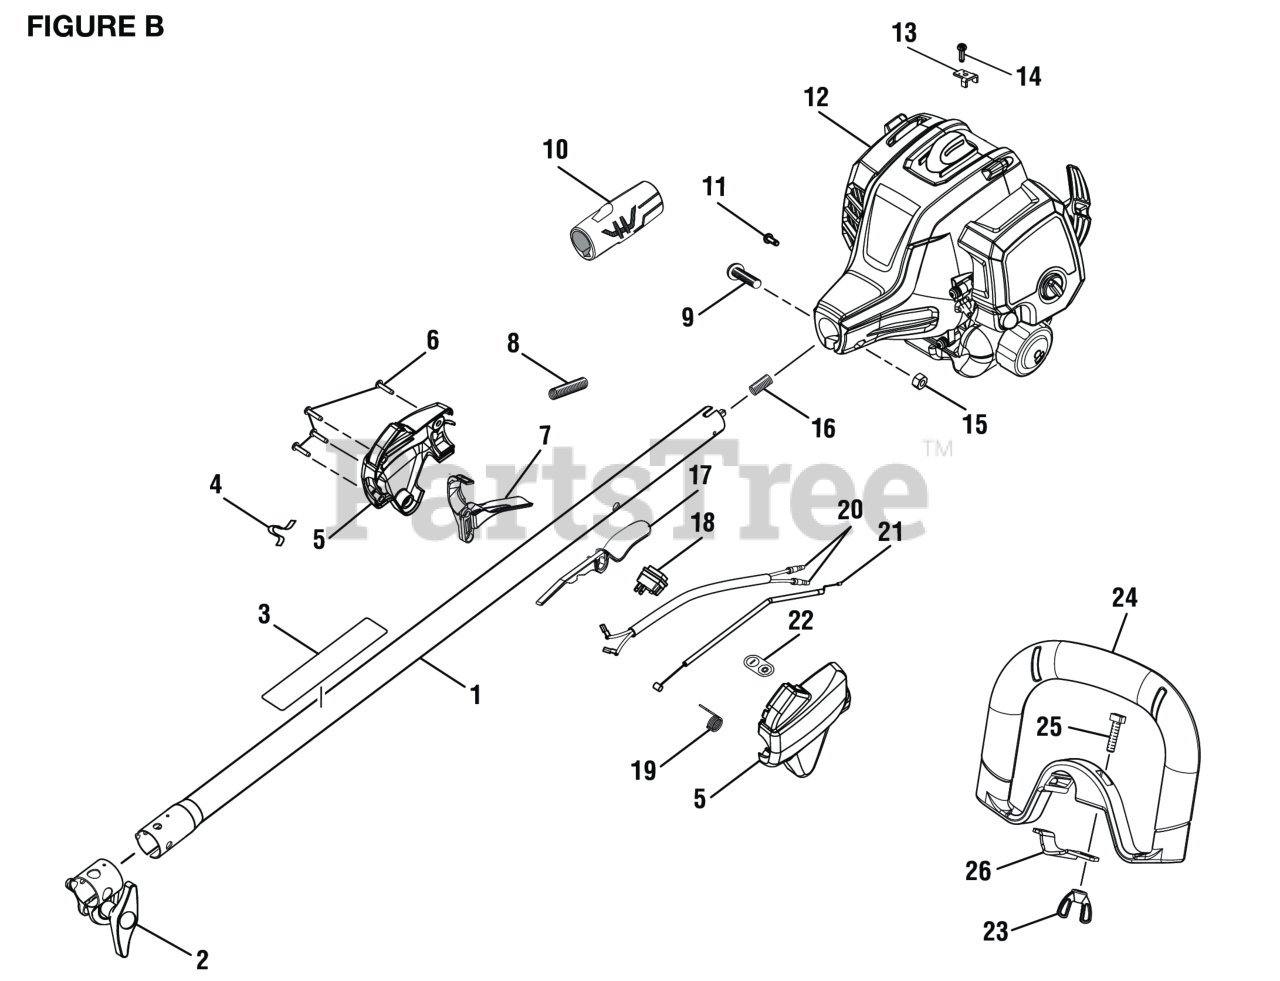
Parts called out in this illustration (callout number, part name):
1	Upper Boom Assembly
2	Boom Clamp Assembly
3	Warning Icon Label
4	Shoulder Strap Hook
5	Control Handle Assembly
6	Screw (M4 x 20 mm, T20 Torx Pan Hd. S.T.)
8	Corrugated Tube (225 mm)
9	Screw (M6 x 30 mm, T27 Torx Button Hd.)
10	Rear Handle Grip
11	Screw (M4 x 8 mm, T25 Torx Pan Hd. T.F.)
12	Powerhead Assembly
13	THROTTLE CABLE CLAMP
14	Screw (M4 x 16 mm, T20 Torx Pan Hd. S.T.)
15	Hex Nut (M6.3 x 1)
16	COMPRESSION SPRING
17	Trigger Lock
18	On/Stop Switch
19	Torsion Spring (Throttle Trigger)
20	Lead Assembly
21	Throttle Cable
22	On/Stop Label
23	Wing Nut (1/4-20, Plastic)
24	Front Handle w/Grip
25	Bolt (1/4-20 x 1 in., Square Hd.)
26	Front Handle Clamp
